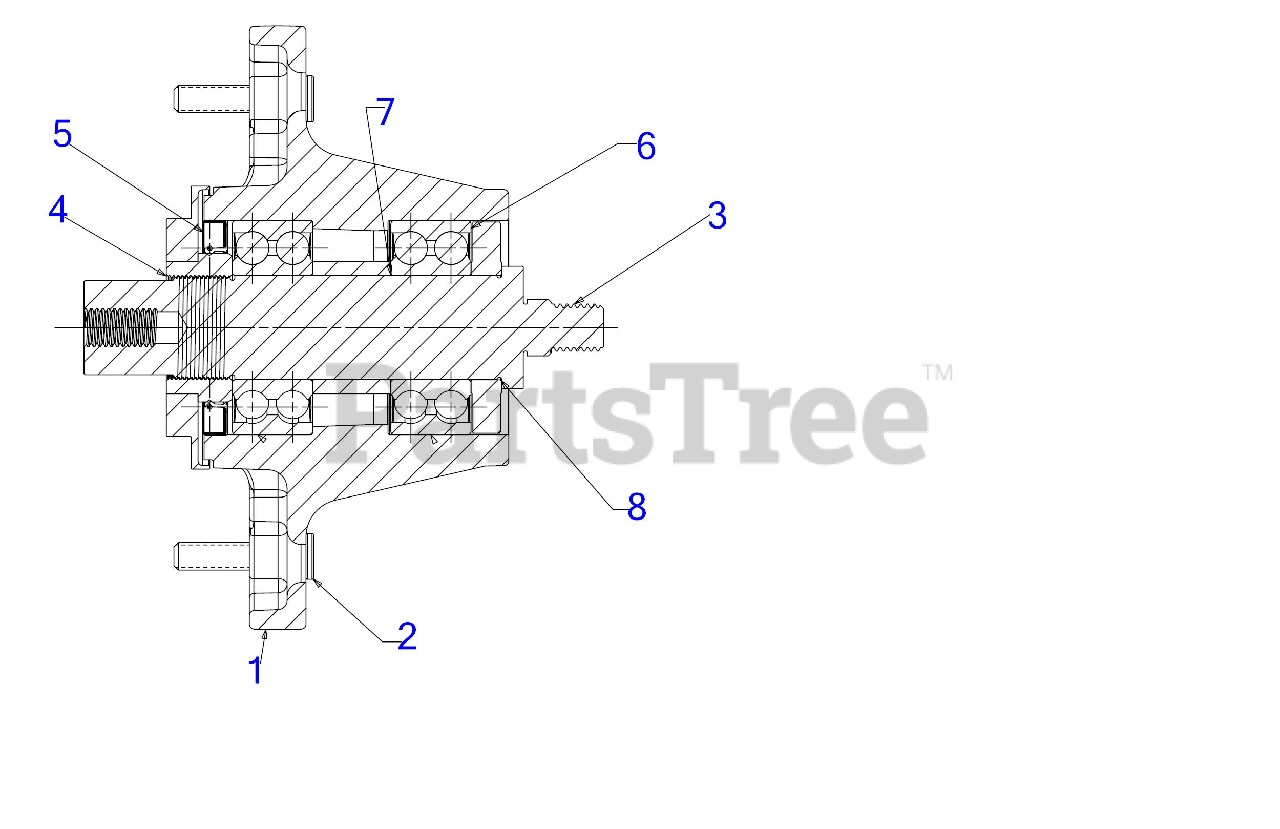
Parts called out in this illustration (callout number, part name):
1	SPINDLE HOUSING
2	STUD 3/8-16 X 1.75
3	SPINDLE SHAFT
4	SHOULDER NUT 1.375-18
5	SEAL 50 X 72 X 8
6	BEARING 35 X 72 X 27
7	SPACER 1.38 X 1.75 X 1.03
8	SPINDLE SHIELD
